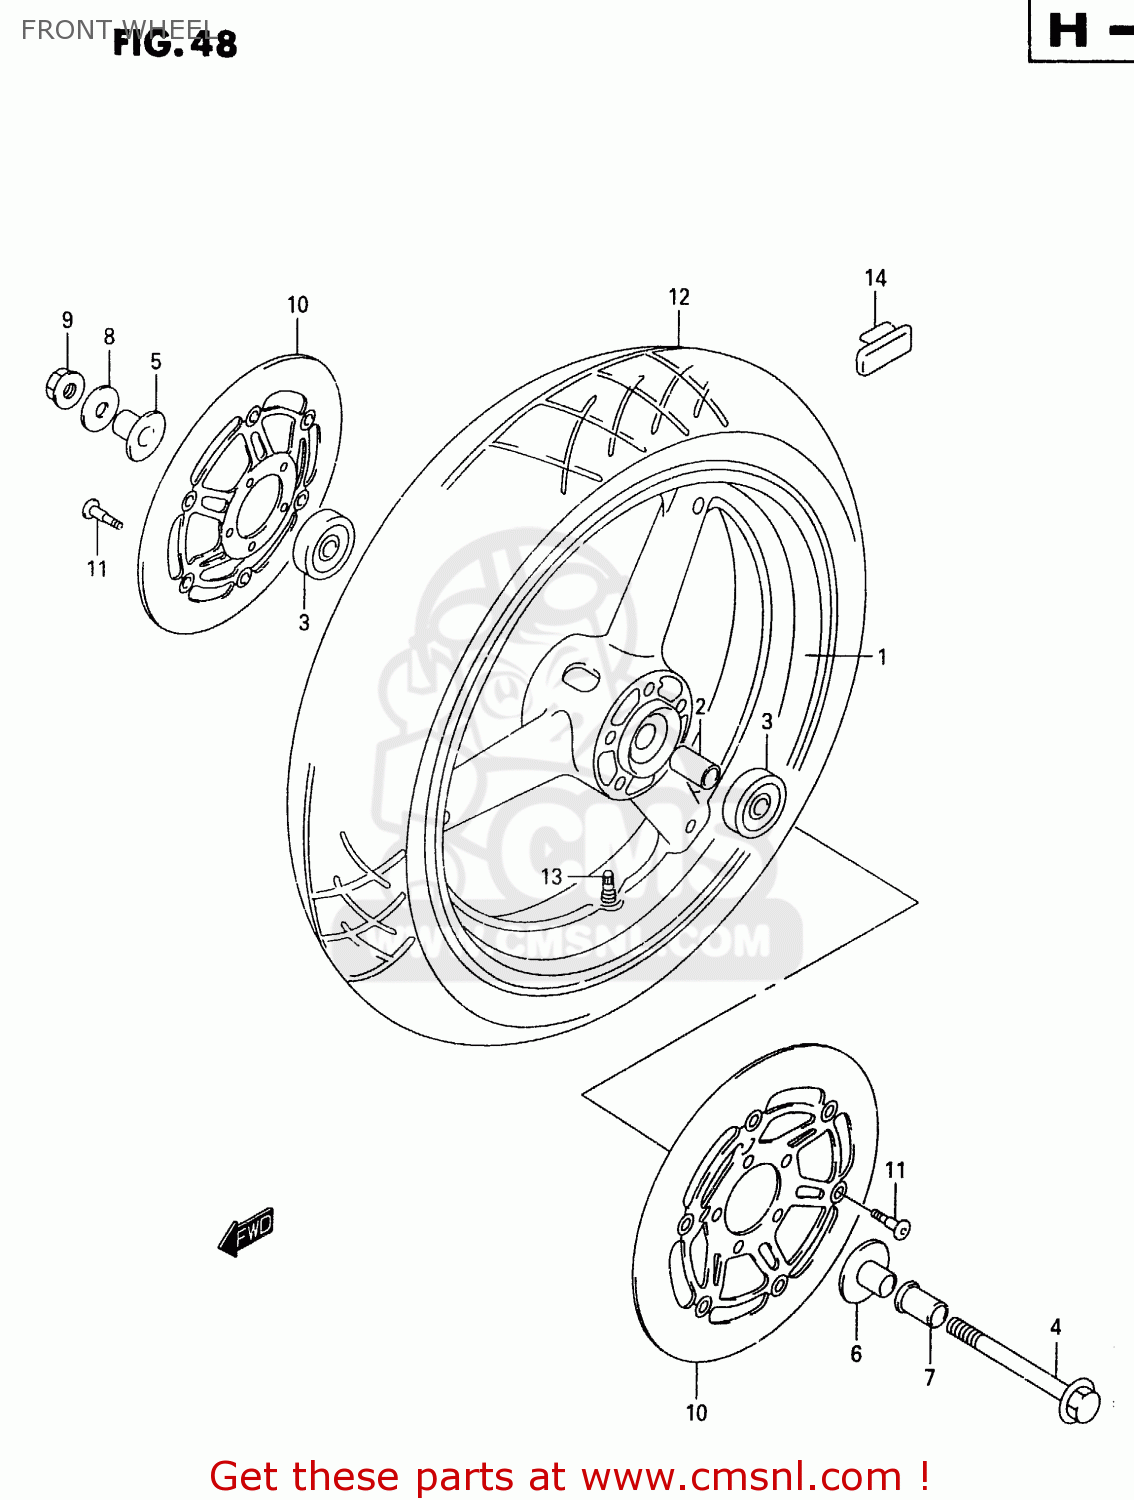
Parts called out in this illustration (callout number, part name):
1	WHEEL,FR(17XMT3.50)
2	SPACER(15.3X21.7X63)
3	BEARING
4	AXLE,FR
5	SPACER,FR AXLE
6	SPACER,FR AXLE,L
7	SPACER,FR AXLE,L
8	WASHER
9	NUT
10	DISC,FR BRAKE
11	BOLT 8X33
12	TIRE 120/70 ZR17 (58W),M
13	VALVE ASSEMBLY,WHEEL,TR412
14	BALANCER,WHEEL (10G)
